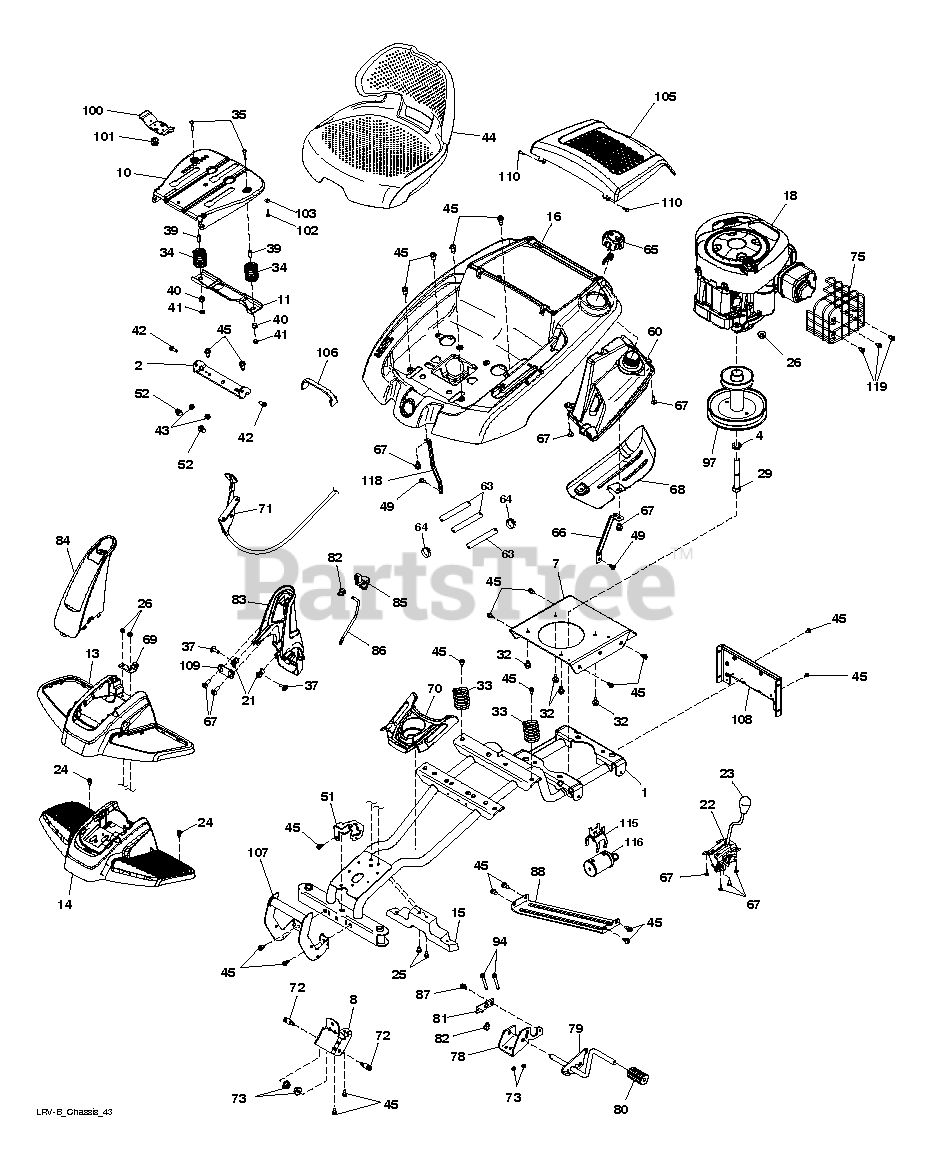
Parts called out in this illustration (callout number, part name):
2	BRKT.PIVOT.FENDER
4	LOCKWASHER
8	BRACKET.SUSP.CHAS.FR.LRV
10	PAN.ASM.SEAT.SHORT.SLD.ADJ.TEX
11	BRKT.MNT.OPC.SW.SEAT.
13	COVER.AESTH.FOOTREST.MS428
14	FOOTREST.STRUCTURAL.
15	SUPPORT. FOOTREST.LRV.MS428
16	PANEL CONTROL ASM.LRVB.GEARDRV
21	Speed Nut, U-Type
22	Clutch Deck Assembly, LRVB
23	KNOB.OVAL.CUSTOM.BLACK
24	SCREW.#10 X 0.750.BOS (2 2)
25	BOLT.CARRIAGE
26	NUT
29	Hex Bolt, 7/16-20 X 3.0 Gr5
32	SCREW.3/8-16
33	SPRING COMPRESSION
34	SPRING COMPRESSED
35	BOLT.ROUND.HEAD.SQUARE.NECK
37	SCREW.PAN.HEAD.#10
39	SPACER SPLIT 28X.96
41	NUT T
42	BOLT.SHOULDER.5/16-18
43	NUT.71038.31-18.HEX.NYLOCK
44	COMFORT.SEAT.ASSEMBLY
45	SCREW
49	SCREW 5/16-18X1
51	STEERING.BRACKET.PNT
52	PUSH CLIP
60	LRVB.FUEL.TANK.ASSEMBLY.EPA
63	RP PURGE LINE
64	HOSE CLAMP
65	CAP.FUEL.2 WAY VENT
67	SCREW.#10 X 0.500
70	CONSOLE.CENTER.CUPHOLDER
72	STUD.FASTNER.W/ANTI-ROTATE
73	NUT LOCK HEX FLANGE 5/16-18
75	GUARD.LRVB.MUFFLER
80	COVER.PEDAL.BRAKE.LRV
82	RETAINER CLIP
87	BOLT.SHOULDER.5/16-18X
88	STRAP.CROSS.FRICTION.DRIVE
94	BOLT HEX FLGHD 5/16-18X3 GR. 5
97	PULLEY.ENGINE.LRVB.PMST
100	HANDLE.SLIDE.SEAT.TEX.BLACK
101	SPRING.LATCH.SEAT.TEX
103	WASHER 13/32 X 2-3/8 X 12GA
105	Engine Cover, Lrvb Pattern 2.X428
106	STRAP.BATTERY.LRVB
107	WELDMENT.FRT.PNT.BRUSHGAD.LR
119	SCREW NO 8-18 X 1/2;HEX WASHER
